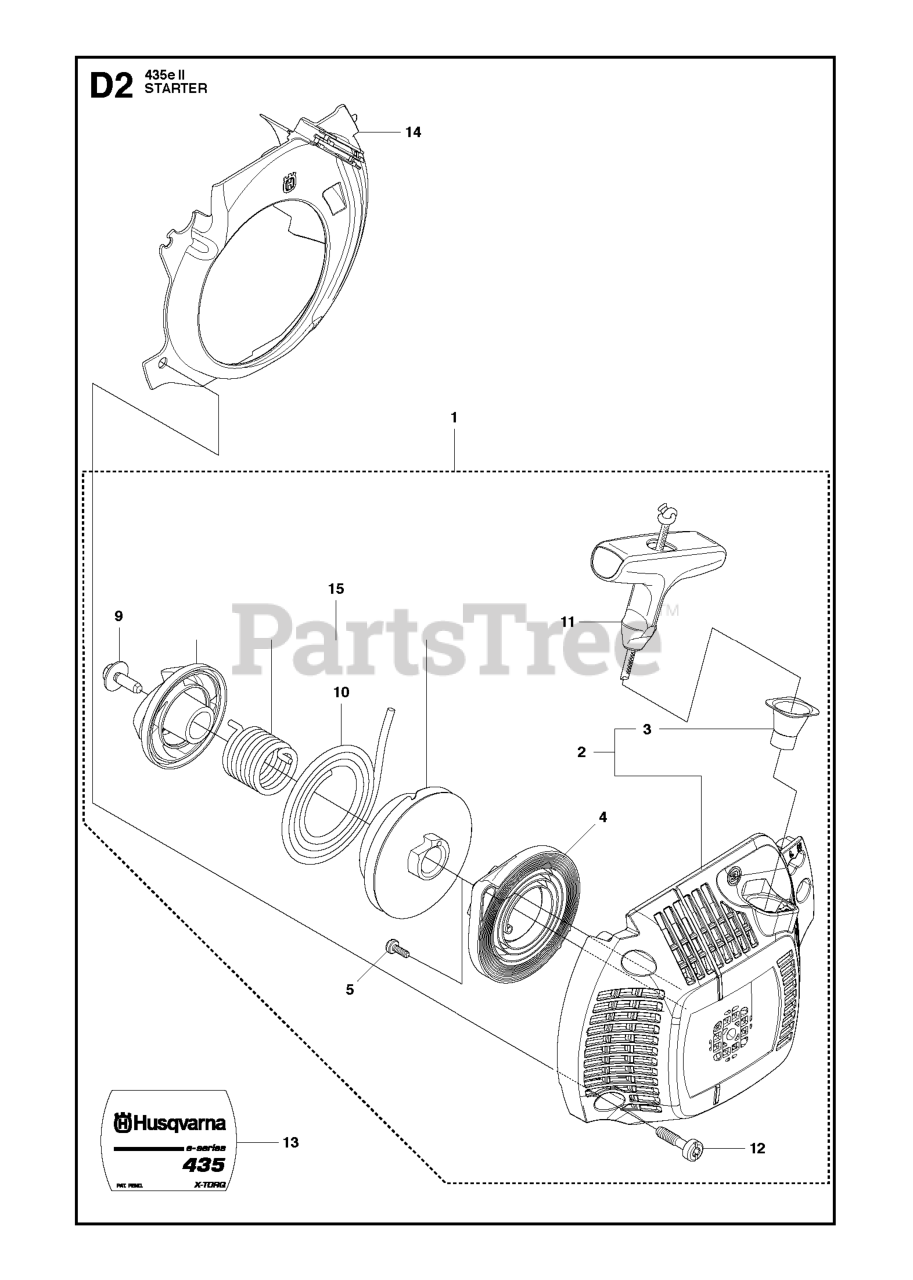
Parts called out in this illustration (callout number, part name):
2	HOUSING STARTER STD
4	SPRING CASSETTE ASSY
10	STARTER ROPE
13	LABEL 435 STARTER
14	COOLING AIR CONDUCTOR
15	STARTER PULLEY KIT WITH SPRING
